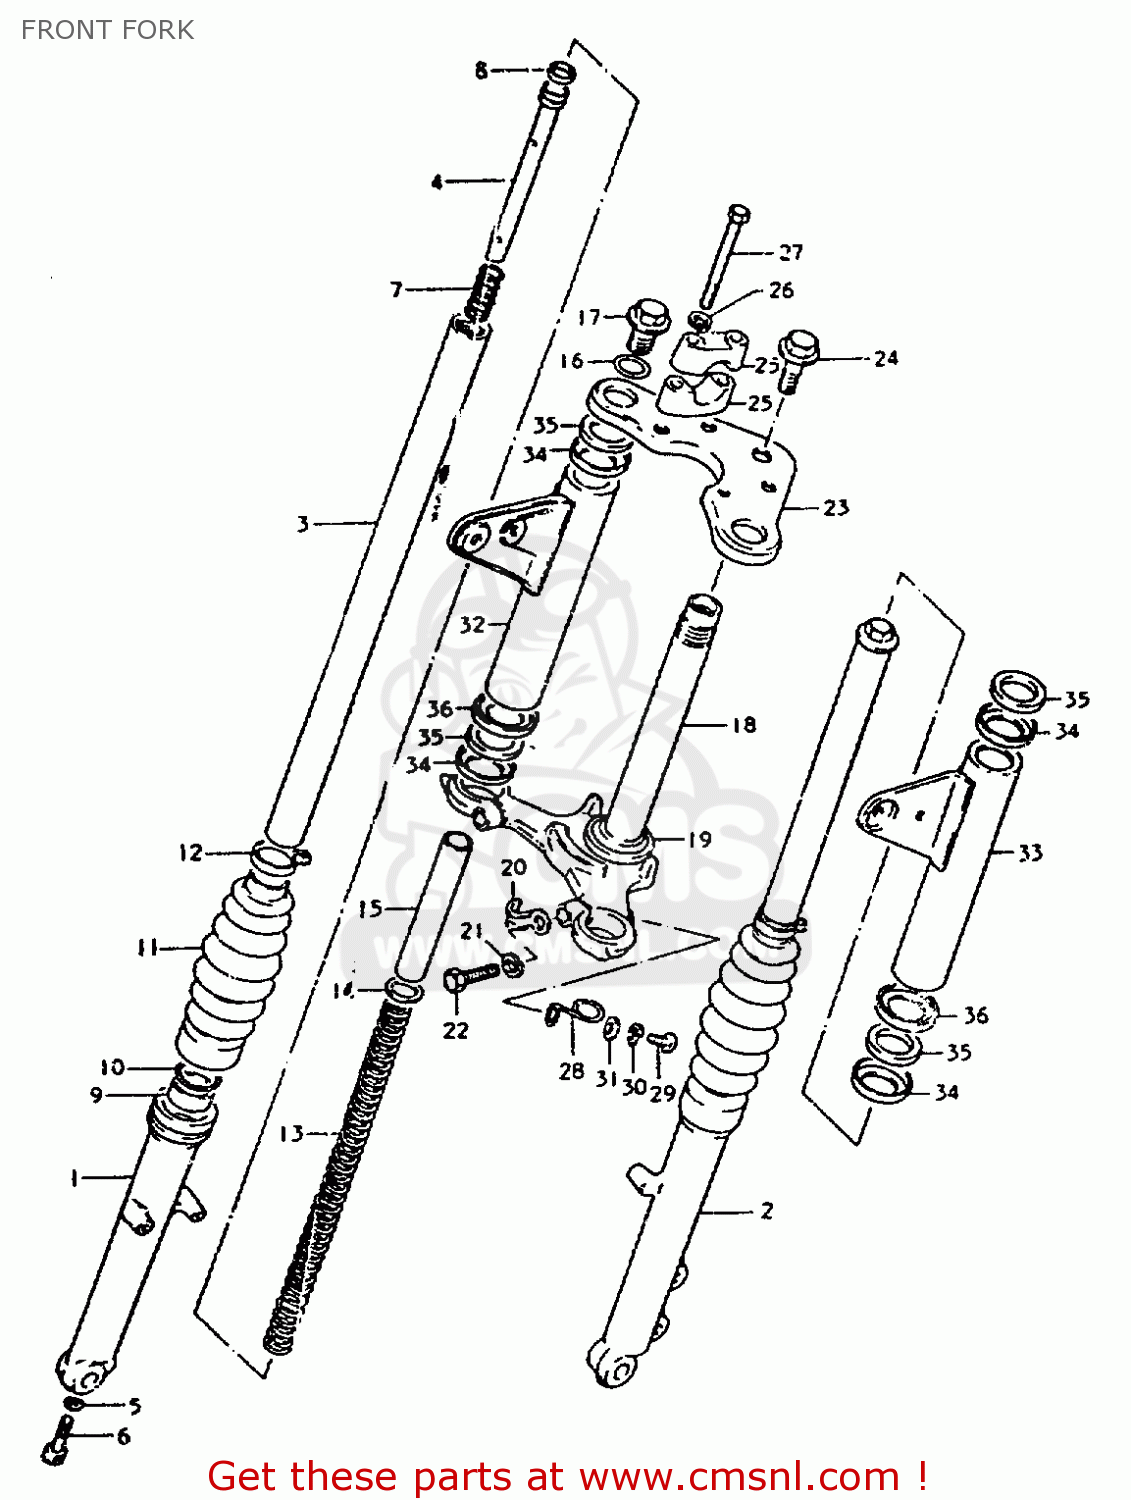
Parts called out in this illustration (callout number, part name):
1	OUTER TUBE, RH
2	OUTER TUBE, LH
3	TUBE,INNER
4	CYLINDER,FRONT FORK
5	GASKET (NAS)
6	BOLT(8X27)
7	SPRING,REBOUND
8	RING,PISTON
9	OIL SEAL,FRONT FORK
10	CIRCLIP,FORK OIL SEAL
11	BOOT
12	BAND
13	SPRING,FRONT FORK
14	JOINT,SPRING
15	SPACER,SPRING
16	O-RING,FORK INNER TUBE
17	CAP
18	STEERING STEM
19	RACE,STEERING OUTER LWR
20	CLIP,CABLE
21	LOCK WASHER
22	BOLT 10X30
23	HEAD,STEERING STEM
24	BOLT
25	HOLDER,HANDLE UPR
26	LOCK WASHER
27	BOLT 8X55
28	CLIP
29	SCREW 6X12
30	LOCK WASHER
31	WASHER
32	BRACKET, HEADLAMP RH
33	BRACKET, HEADLAMP LH
34	SEAT, CUSHION
35	CUSHION
36	SEAT, HEADLAMP BRACKET
